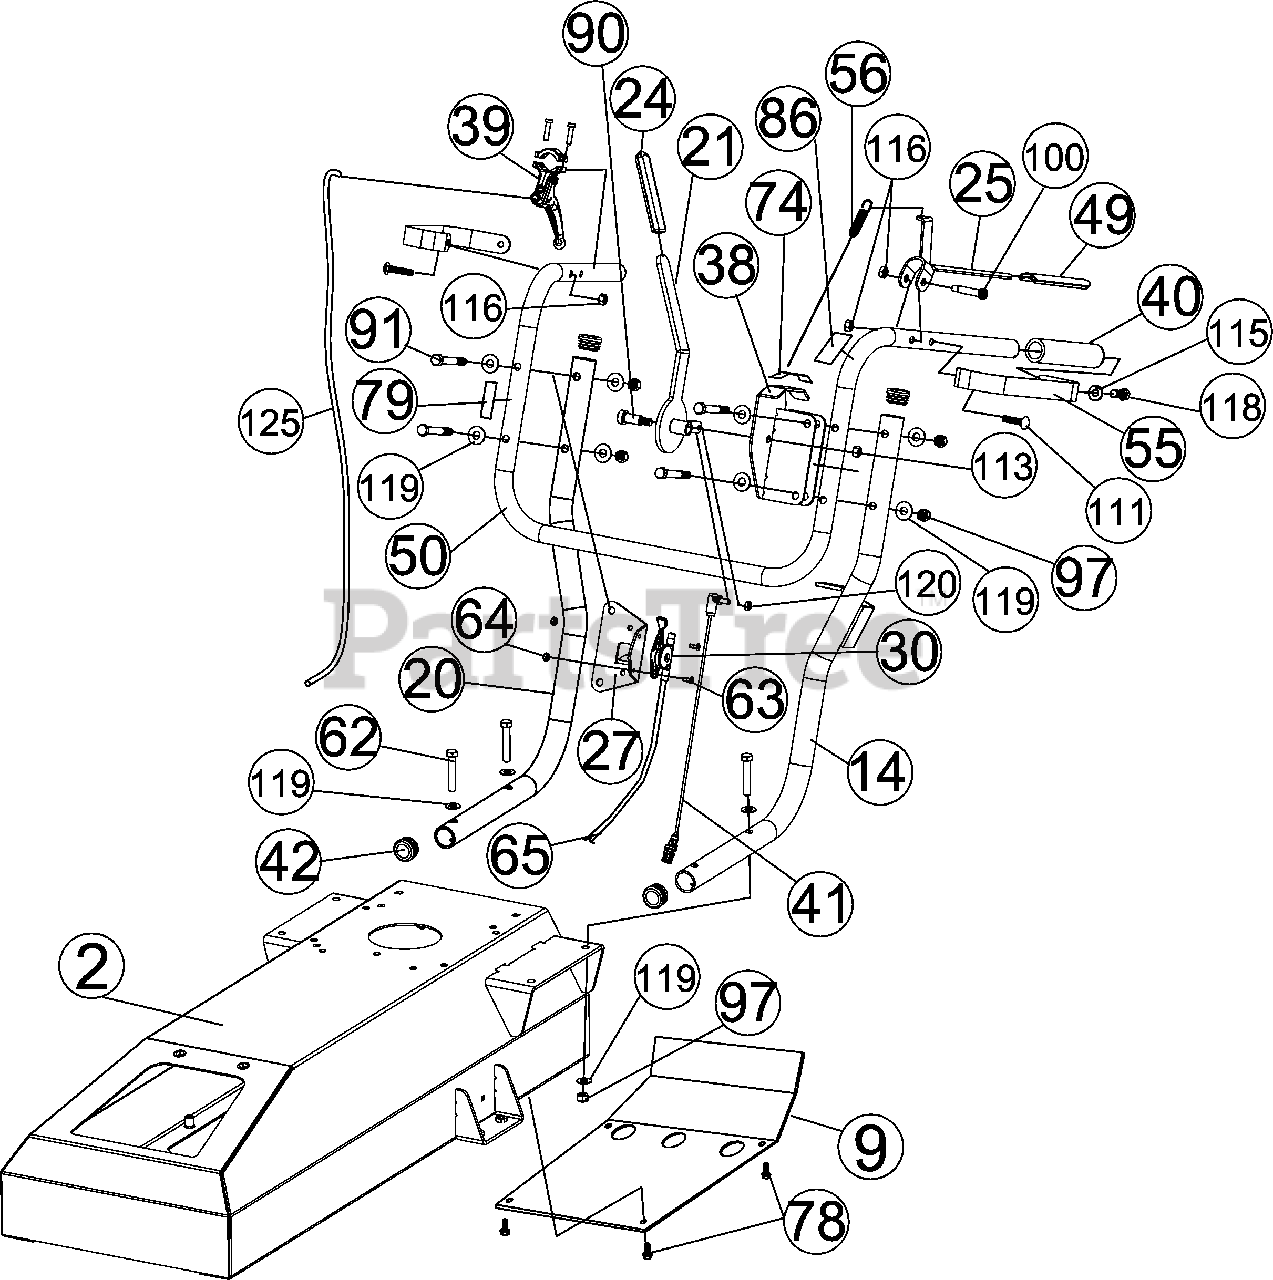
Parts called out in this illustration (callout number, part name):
2	BASE ENGINE BC26 FIXED WA W/LABELS
9	GUARD REAR BC26
14	PLATE CLAMP SKIRTING BC26
20	HANDLE LOWER RIGHT
21	LEVER SHIFTER WA BC26
24	GRIP LEVER 1" X 4.25"
25	LEVER CONTROL BLADE LIGHT
27	BRACKET THROTTLE BC26
30	CONTROL THROTTLE
38	BRACKET SHIFTER WA W/LABELS
39	CONTROL MAGURA OS900SP
40	GRIP HANDLE 1" X 5.5"
41	CABLE CONTROL SHIFTER BC26
42	PLUG TUBE INSERT 1.25 OD
49	GRIP LEVER 0.125" X 1" X 5" ORANGE
50	HANDLE UPPER
55	GUARD HAND BC26
56	CABLE CLUTCH BC26
62	SCREWCAP 3/8"- 16 X 2"
63	SCREW MACH #10 - 24 FLAT HD
64	NUT LOCK LT #10 - 24 HEX
65	CABLE THROTTLE CONTROL 25.5
74	LABEL SHIFT BC26 MECH
78	SCREW SELT TAP 1/4"-20 X 5/8 HWH TYPE F
79	LABEL THROTTLE
86	LABEL CLUTCH BLADE
90	BOLT SHOULDER 1/2" X 1"
91	SCREWCAP 3/8"-16 X 3" HCS ZP
97	NUT LOCK 3/8"-16 HEX
100	BOLT SHOULDER 3/8"- 16 X 1 1/2"
111	BOLT CARRIAGE 5/16"- 18 X 1 1/2" ZP
113	NUT LOCK 3/8"- 16 LT WT TH ZP
115	WASHER LOCK 5/16" S/T MED
116	NUT LOCK 5/16"-18 HEX ZP
118	SCREWCAP 5/16"- 18 X 1"
119	WASHER 3/8" FC
120	NUT LOCK 1/4"- 28 TH ZP
125	CABLE DRIVE BC26
